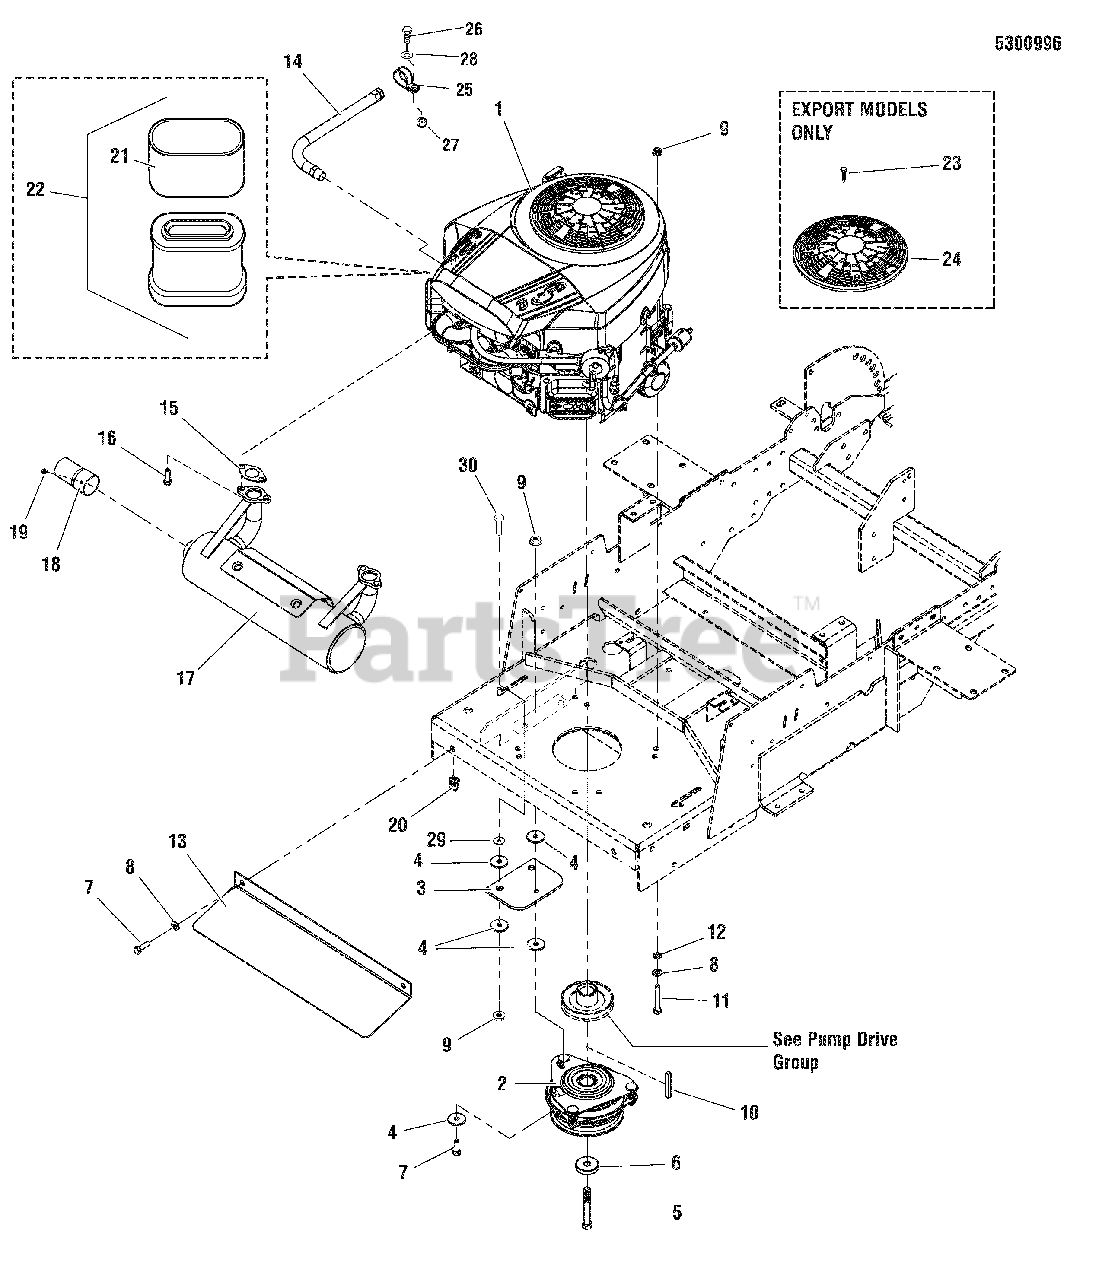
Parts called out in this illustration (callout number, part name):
1	* ENGINE, B&S, ELS
2	CLUTCH, #51110100, ELECTRIC, 1" SHAFT
3	CLUTCH ANCHOR PAD
4	WASHER, .34 X 1.25 X 10 GA
5	BOLT, CRANKSHAFT, 7/16-20 X 3-1/4"
6	SPACER, .45 X 1.62 X .37
7	BOLT, 5/16-18 X 1 GD5 YZ
8	WASHER, 5/16" SAE
9	NUT, 5/16-18 HEX NYLOCK FLANGE
10	KEY, 1/4" SQ. X 2 1/4
11	BOLT, 5/16-18 X 2-1/4" GD 5 YZ
12	WASHER, 5/16" INT. TOOTH LOCK
13	PLATE, HEAT SHIELD - RED
14	HOSE, OIL DRAIN
15	GASKET, Exhaust
17	MUFFLER, B&S-ELS
18	EXTENSION, TAILPIPE, 3" - BLACK
19	SCREW
20	BODY CLIP, 5/16-18 X 1/2 DEEP
21	* PRE CLEANER (SV)
22	* AIR CLEANER W/ PRE CLEANER (SV)
23	* SCREW, CROSS RECESSED THREAD
24	COVER, STATIC / LABEL ASSY
29	NUT, 5/16-18 HEX SERRATED FLANGE (LARGE)
30	BOLT, 5/16-18 X 1-1/4 GD5 YZ
